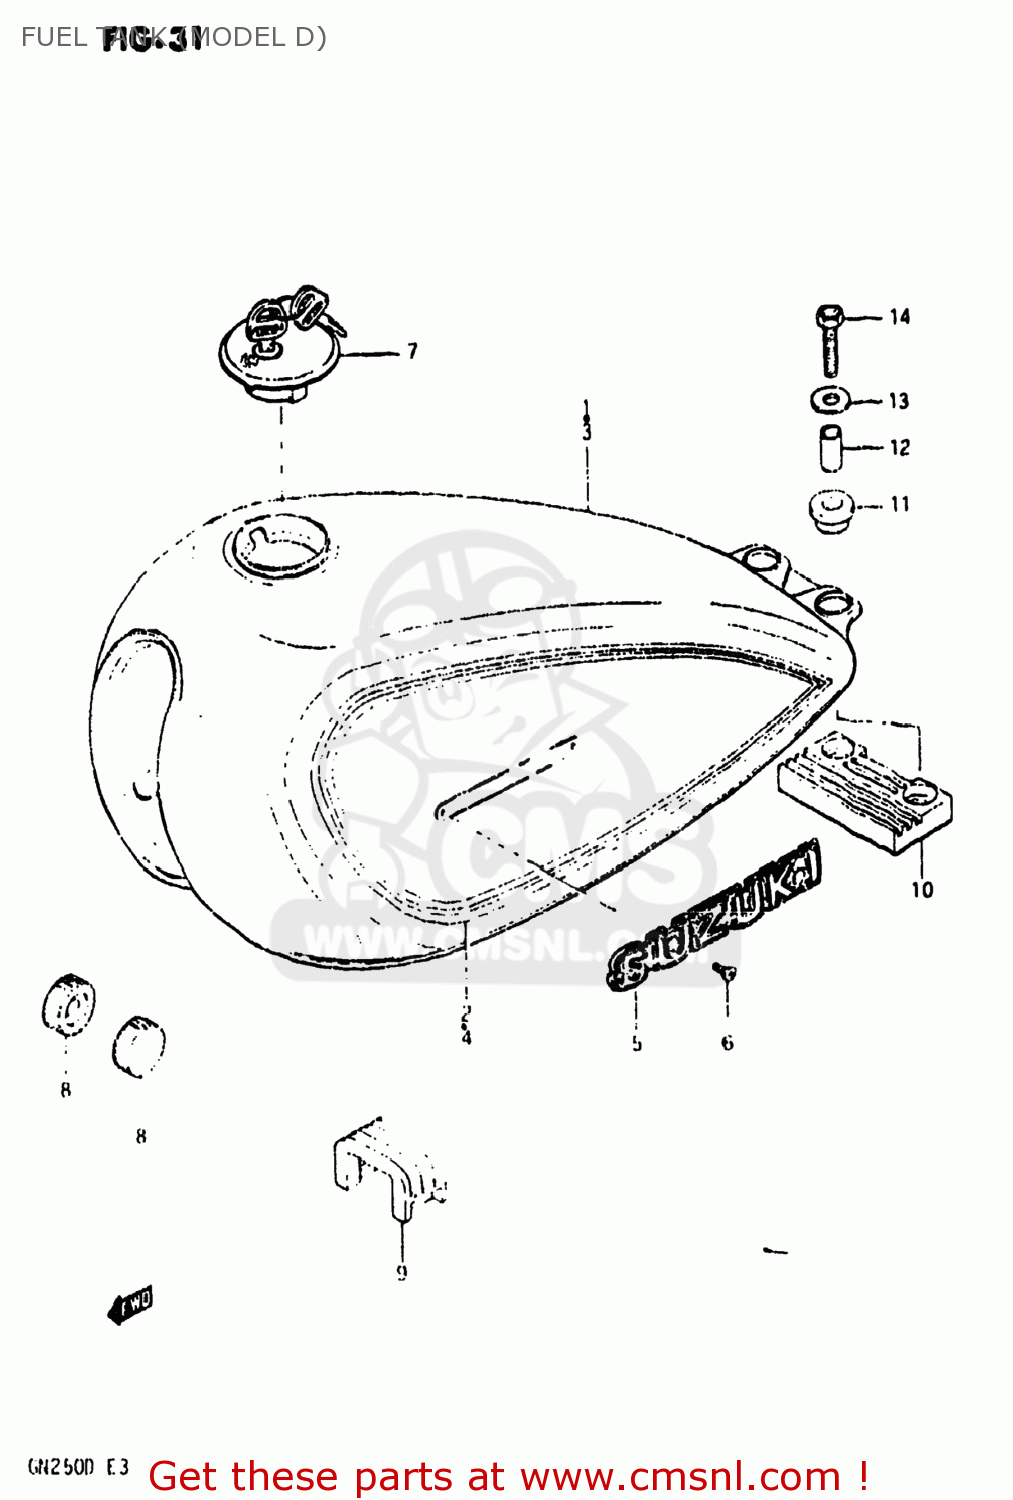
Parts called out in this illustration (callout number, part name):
1	TANK ASSEMBLY,FUEL
2	TAPE SET,FUEL TANK
3	TANK ASSEMBLY,FUEL
4	TAPE SET,FUEL TANK
5	EMBLEM,FUEL TANK
6	SCREW 3X6
7	CAP SET,FUEL TANK
8	CUSHION
9	CUSHION,TANK UPR FR
10	CUSHION,TANK RR NO.1
11	CUSHION
12	SPACER(6.5X10.5X22.5)
13	WASHER(6,5X22X1.6)
14	BOLT(6X35)
